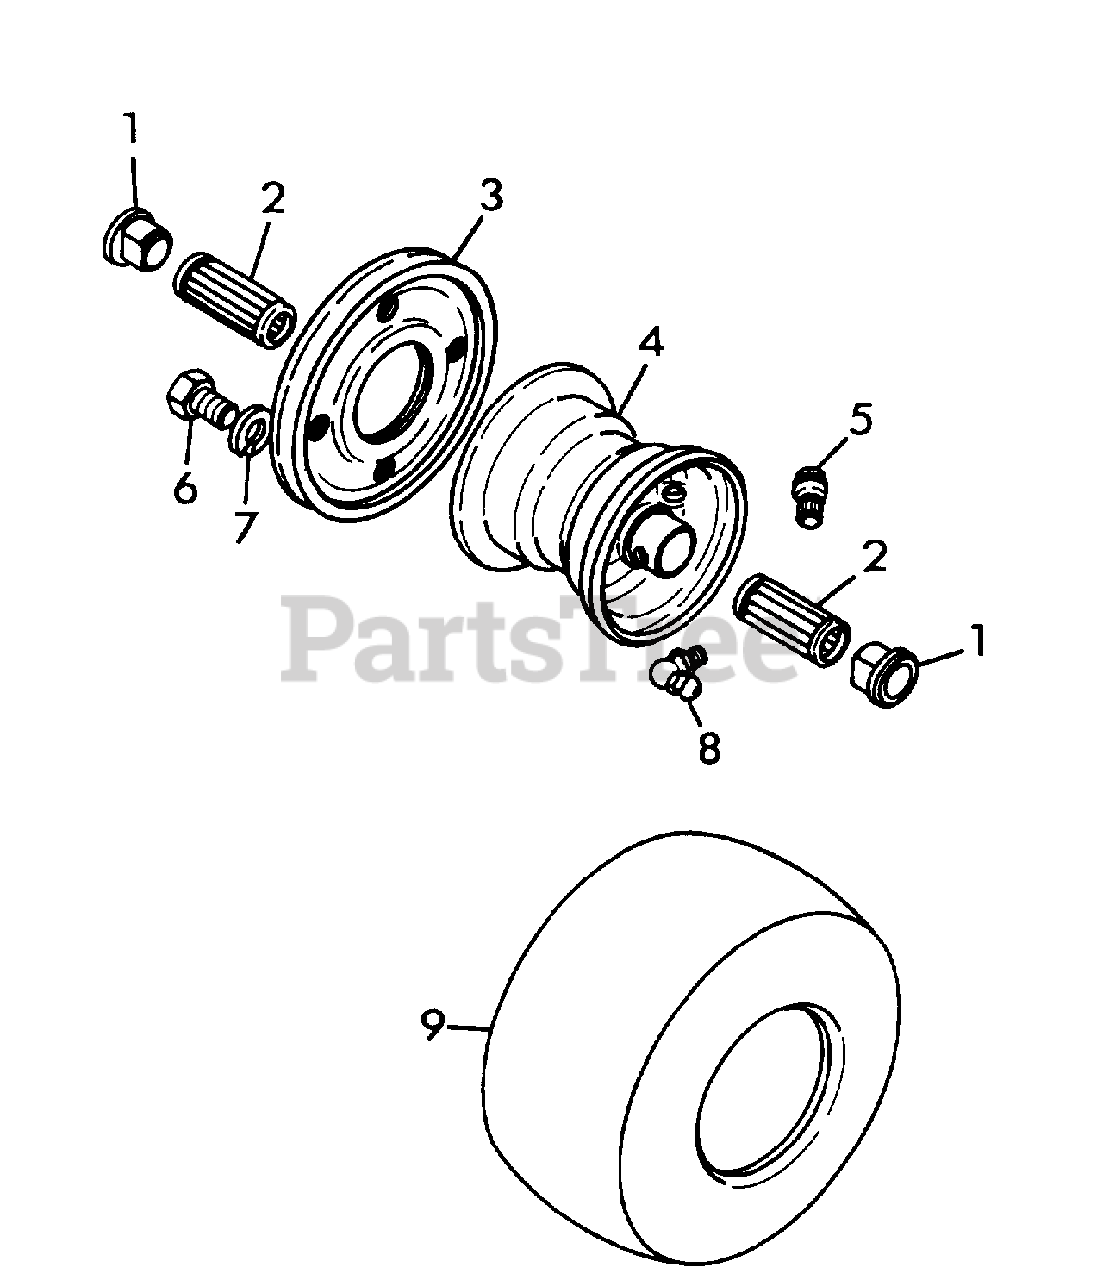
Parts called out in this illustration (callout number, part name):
1	BEARING, FLANGE
2	BEARING, 7/8X2.50
3	ASSEMBLY, PULLEY AND BRAKE DRUM
4	ASSEMBLY, WHEEL
5	ASSEMBLY, VALVE STEM
6	BOLT, HEX 5/16-18X.75
7	WASHER, LOCK 5/16 REG.
8	FITTING, LUBE 90 DEG.
9	TIRE, 13X6.50-6
